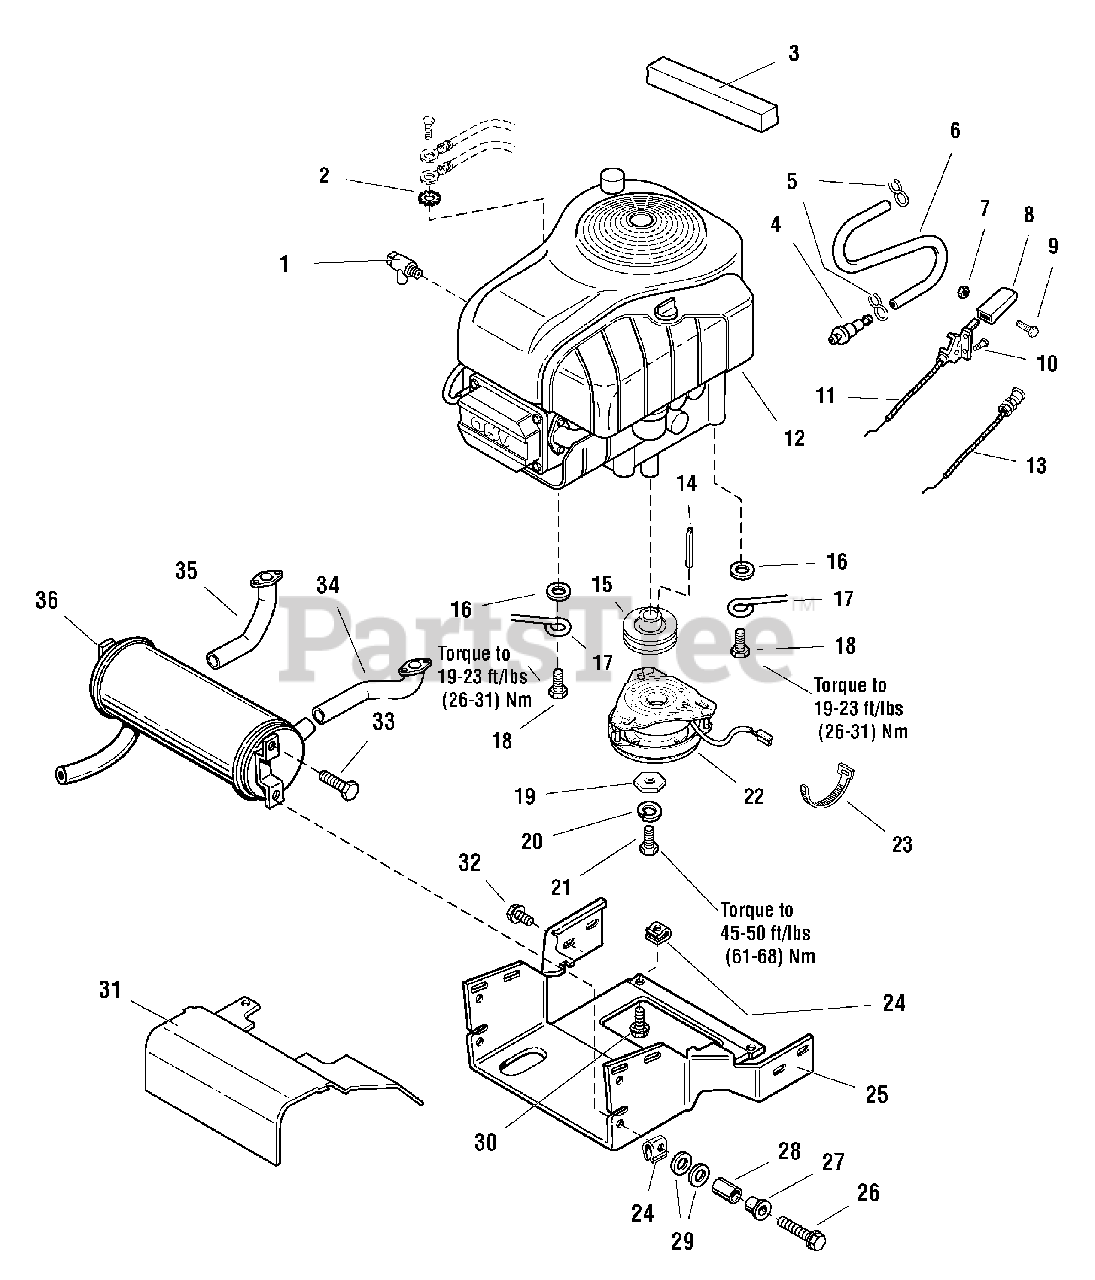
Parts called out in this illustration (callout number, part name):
1	VALVE-SHUT OFF
2	LOCKWASHER, External Tooth 3/8
4	FILTER, Fuel
5	CLAMP, Hose Type E
6	HOSE, 12~ Long
7	NUT-HEX LOCK 10-24 W/NYL INSRT NC3B BLK
9	SCREW-PAN HD PHILLIPS#10-24X1.000 BLK
10	CAPSCREW, Hex Washer Head 1/4-14 x 5/8
11	CABLE, Throttle Control
12	ENGINE-18HP Briggs & Stratton INTEK SINGLE
13	CABLE, Choke, 16~ Long
14	KEY, Hydro Only
15	PULLEY, Hydro Only
16	WASHER
17	STOP-BELT .213WIRE 3.12 ,0.75 BLK
18	CAPSCREW, Hex Washer Head, Taptite, 3/8-16 x 1-1/2
19	WASHER-HEX 0.453ID X 1.500A/F .250TH BLK
20	LOCKWASHER, 7/16
21	CAPSCREW, 7/16-20 x 3
22	CLUTCH-ELECTRIC REGENT,BROADMOOR OGURA
23	TIE-SELF LOCKING .184WD 7.31LG BLACK ZY
24	NUT, Speed 5/16-18
25	DUCT, Muffler
26	CAPSCREW, Hex Flange Lock, 5/16-18 x 1-1/4
30	CAPSCREW, Hex Flange Lock, 5/16-18 x 3/4
31	DUCT,Muffler, Upper
32	CAPSCREW, Hex Washer Head, Taptite, 5/16-18 x 1/2
33	CAPSCREW, Hex Washer Head, Taptite, 1/4-20 x 3/8
34	MANIFOLD, Pipe L.H.
35	MANIFOLD, Pipe R.H.
